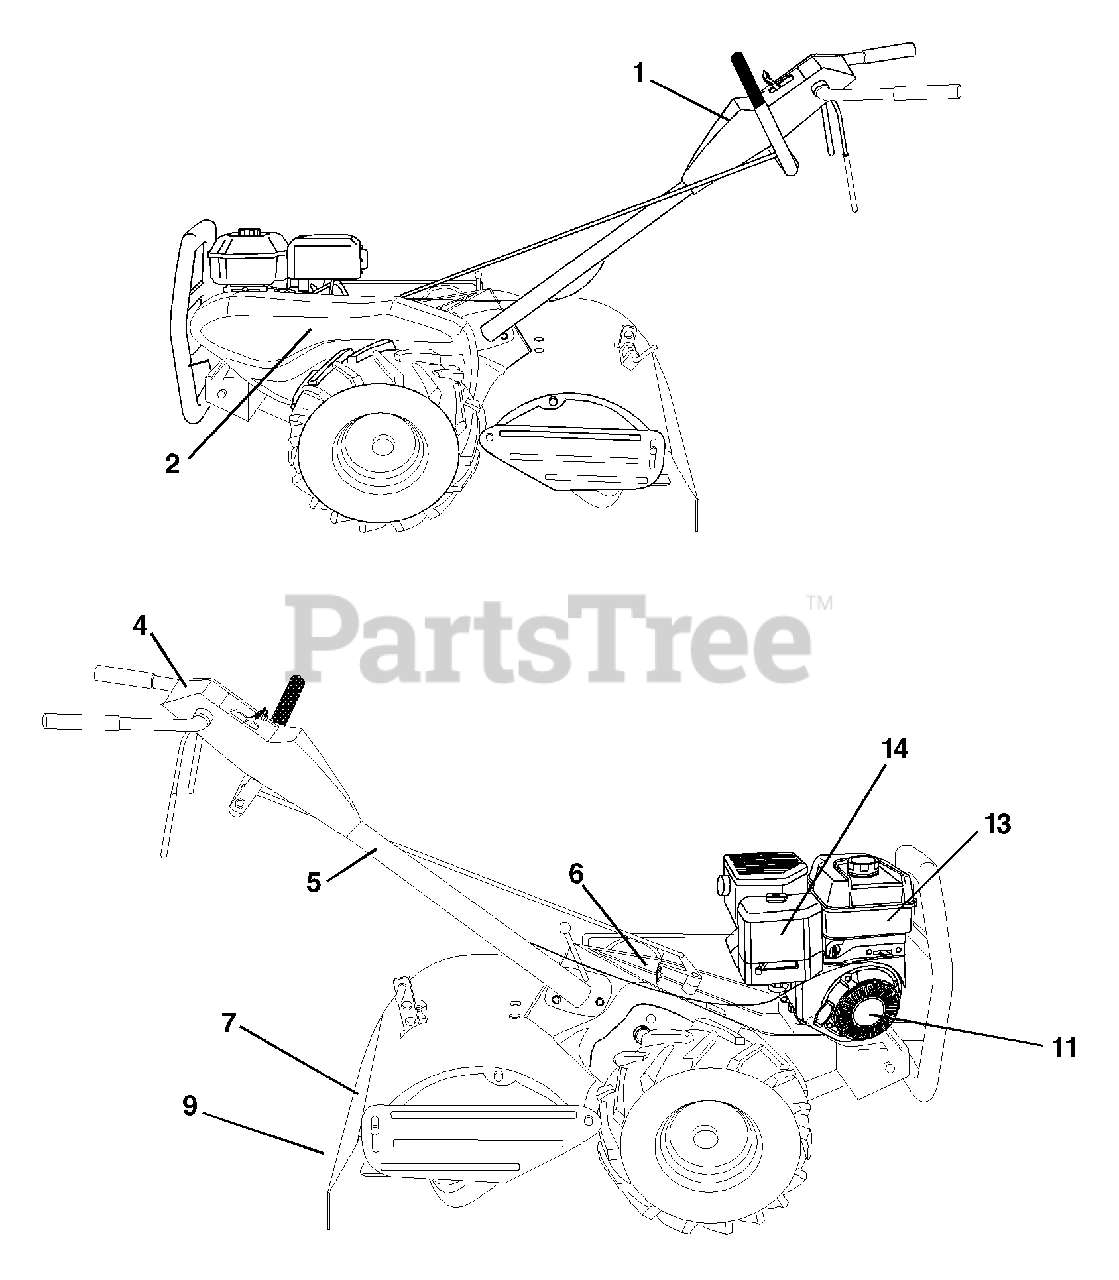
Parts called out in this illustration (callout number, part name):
1	Decal, CNTRL PNL
2	Decal, Decal, Blt Grd
4	Decal, Instruction, Tilling
5	Decal, Hand Placement
6	Decal, Shift Indicator
7	Decal, caution
9	Decal, Warning, Rotating Tines
11	Decal, Rewind
13	Decal, B&S Tank
14	Decal, B&S Air Cleaner
